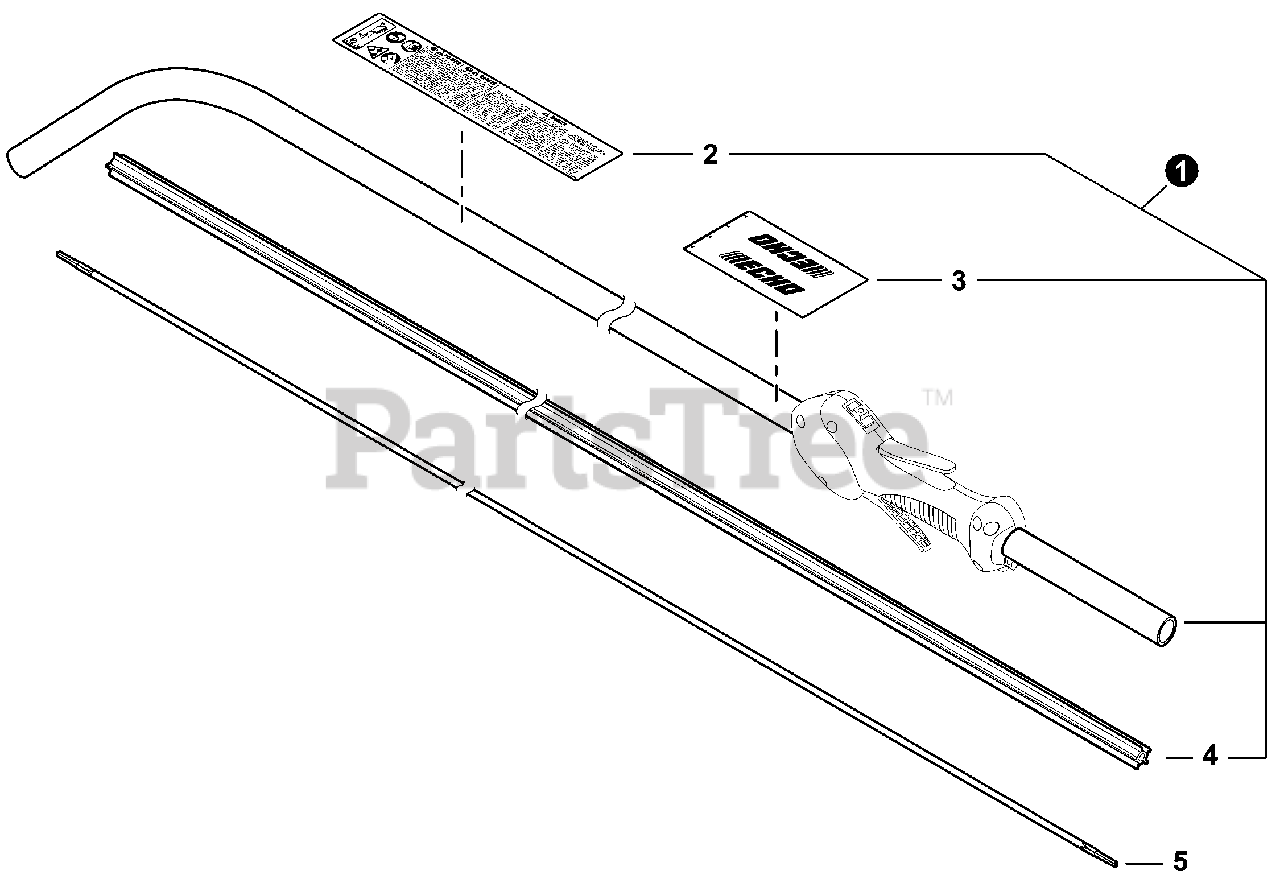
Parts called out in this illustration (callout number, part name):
1	MAIN PIPE ASSY
2	LABEL, CAUTION
3	LABEL, HANDLE LOCATION
4	LINER - FLEXIBLE
5	DRIVESHAFT - FLEXIBLE
